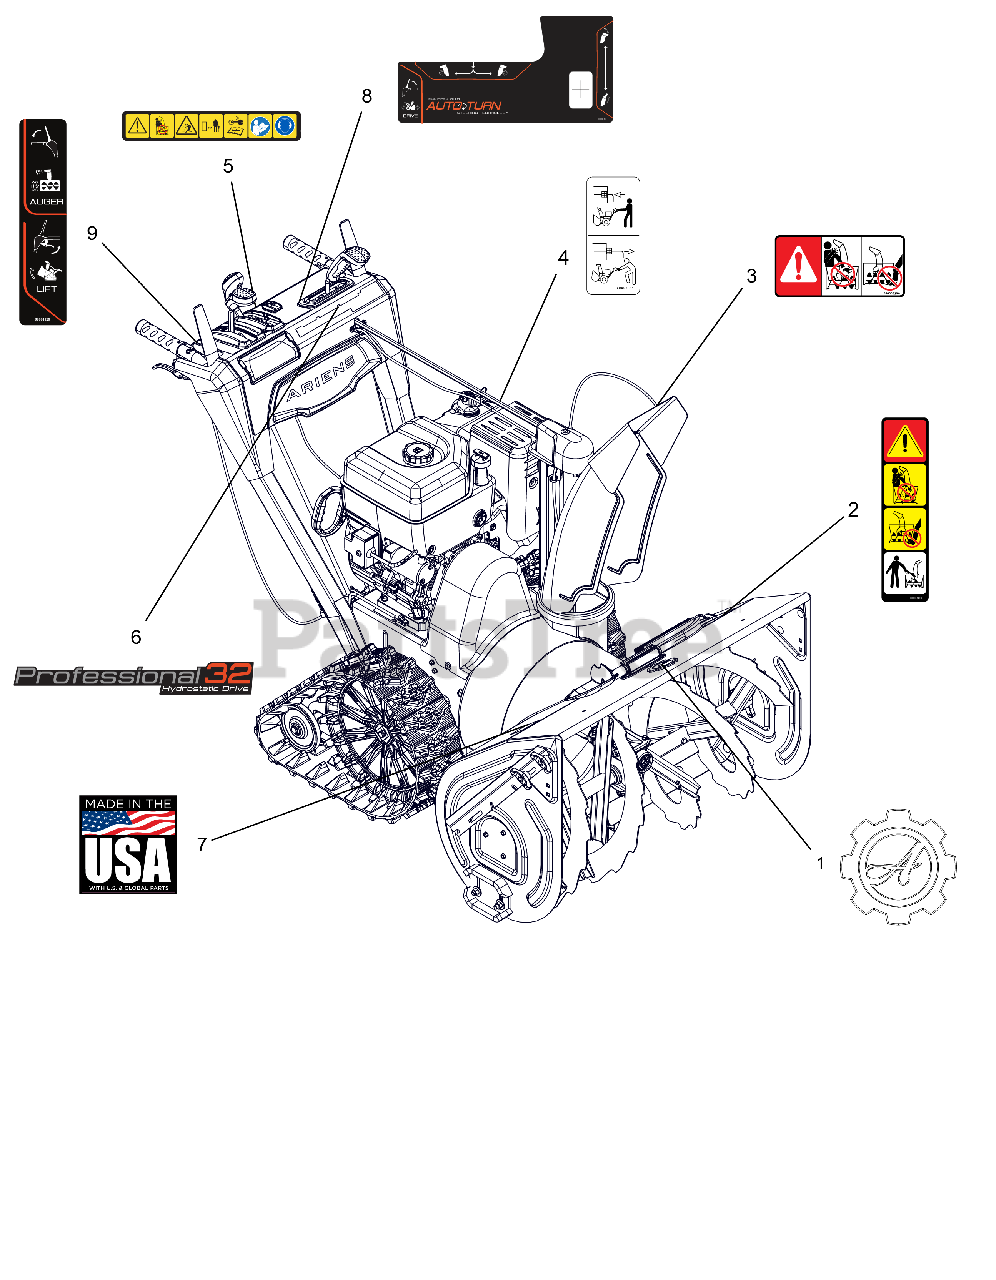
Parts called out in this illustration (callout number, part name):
1	DECAL, ARIENS-GEAR BADGE -THK
2	DECAL, DANGER - ROTATING PARTS
3	DECAL, DANGER
4	DECAL, BYPASS
5	DECAL,DASH - SAFETY
6	DECAL, DASH - PRO HYDRO 32
7	DECAL, MADE IN USA
8	DECAL,CONTROL-LG QT2
9	DECAL,CONTROL-RH TRACK
